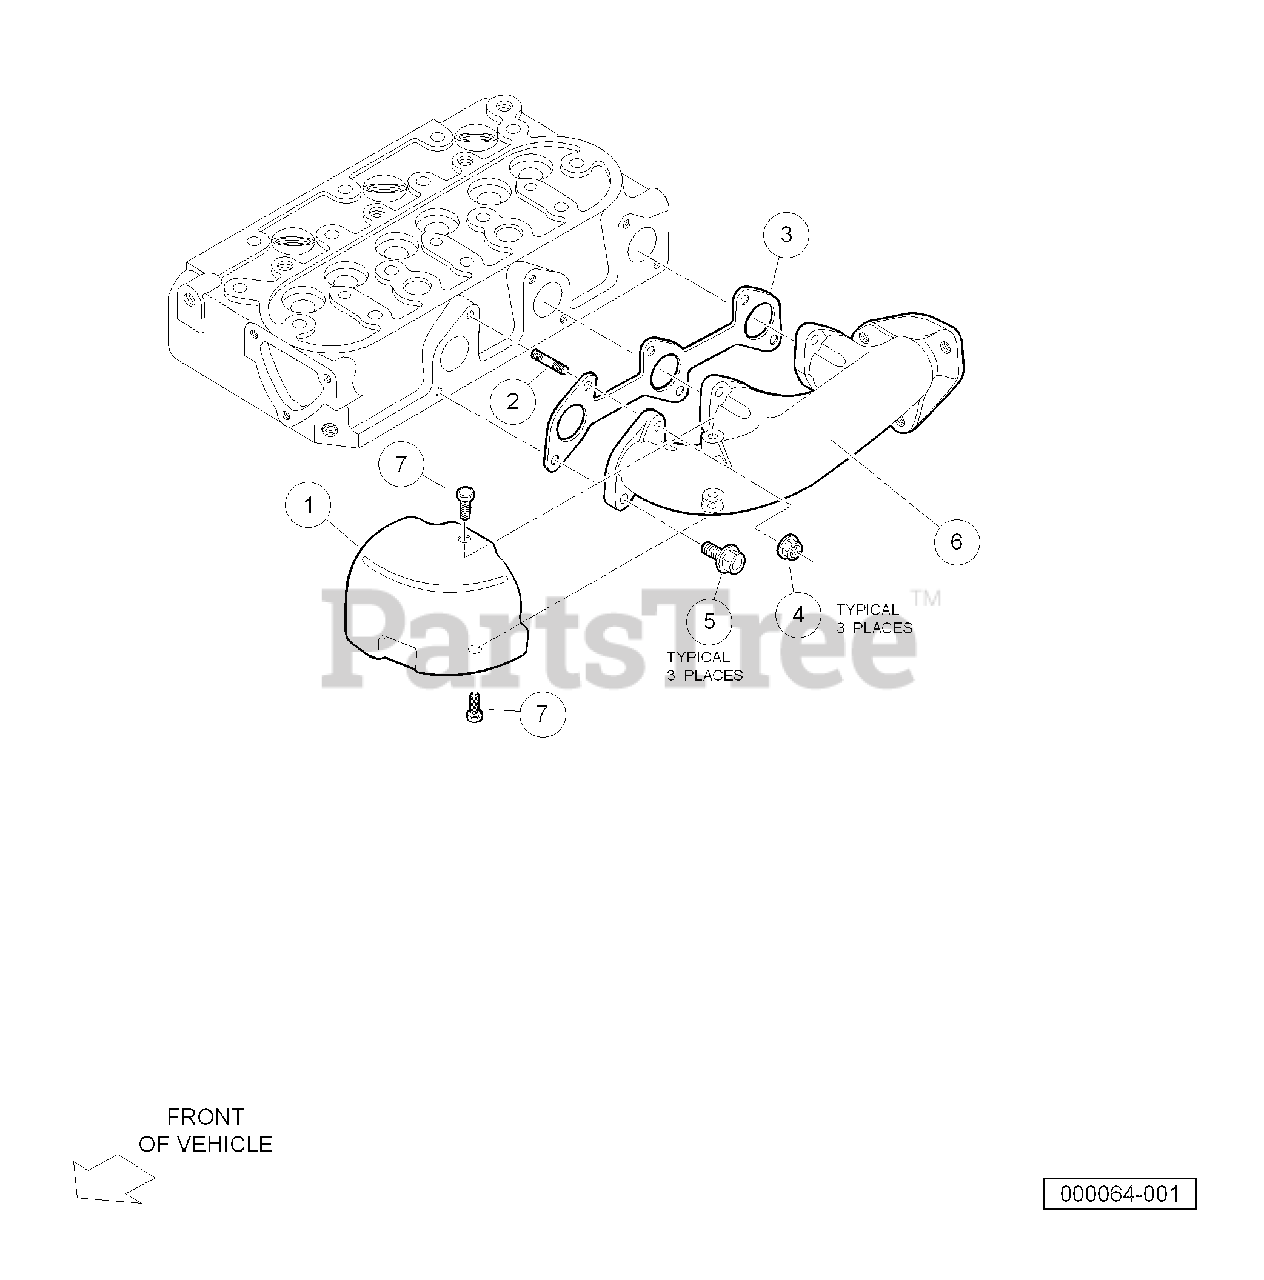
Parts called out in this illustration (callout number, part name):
1	Covgt, Heat Proof
2	Stud, M6 X 26
3	Gasket, Ex-manifold
4	Nut, Flange, M6, Ubs
5	Bolt, Flange Head, M6 X 1 X 16
6	Manifold, Exhaust, D722
7	Bolt, D722, Exhst Manfld Cover
